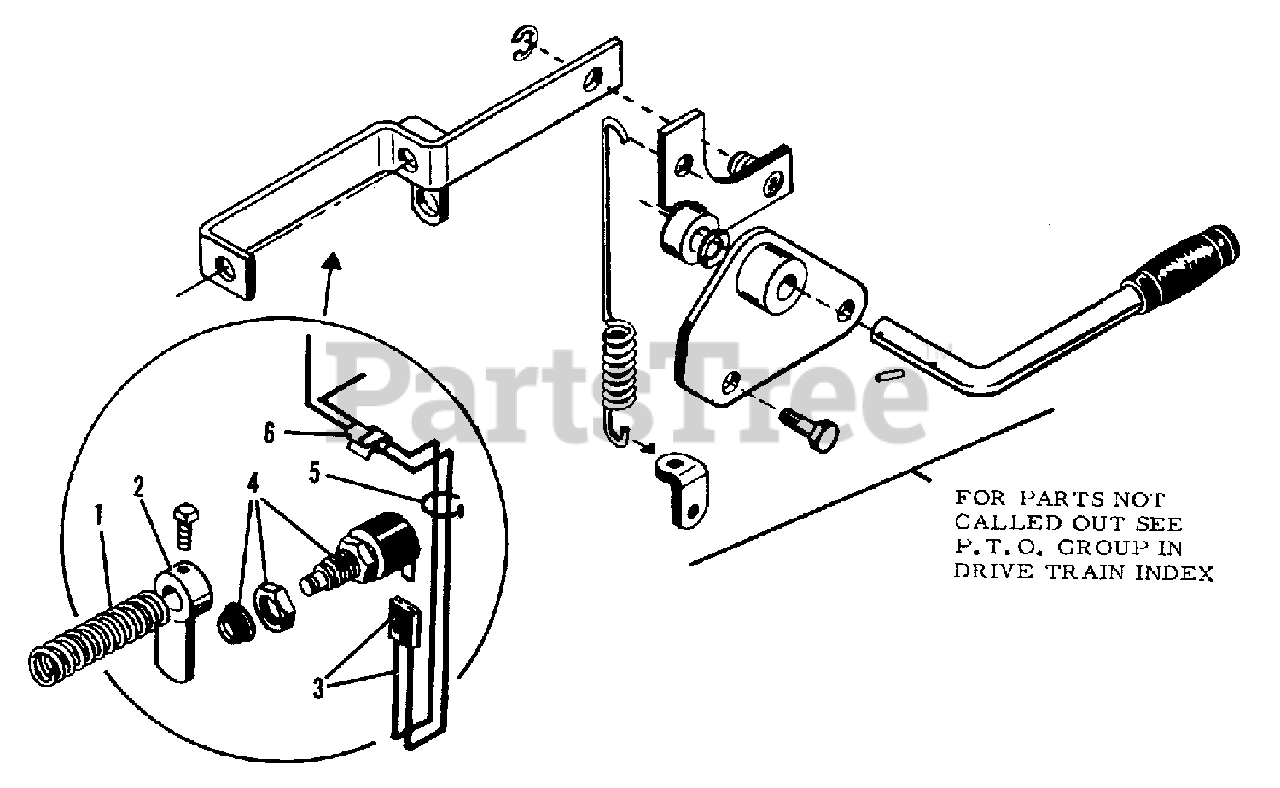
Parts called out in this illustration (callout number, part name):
1	*SPRING, Compression
1	*WASHER, 17/32 x 1 x 20 Ga.
1	*PIN, Quick
2	*STOP ASSEMBLY, P.T.O. Control Rod
3	LEAD, Manual P.T.O. Interlock Switch
4	SWITCH, Momentary
4	NUT, Hex, Special
4	BOOT, Rubber
5	TIE, Cable
6	CLIP, Cable
